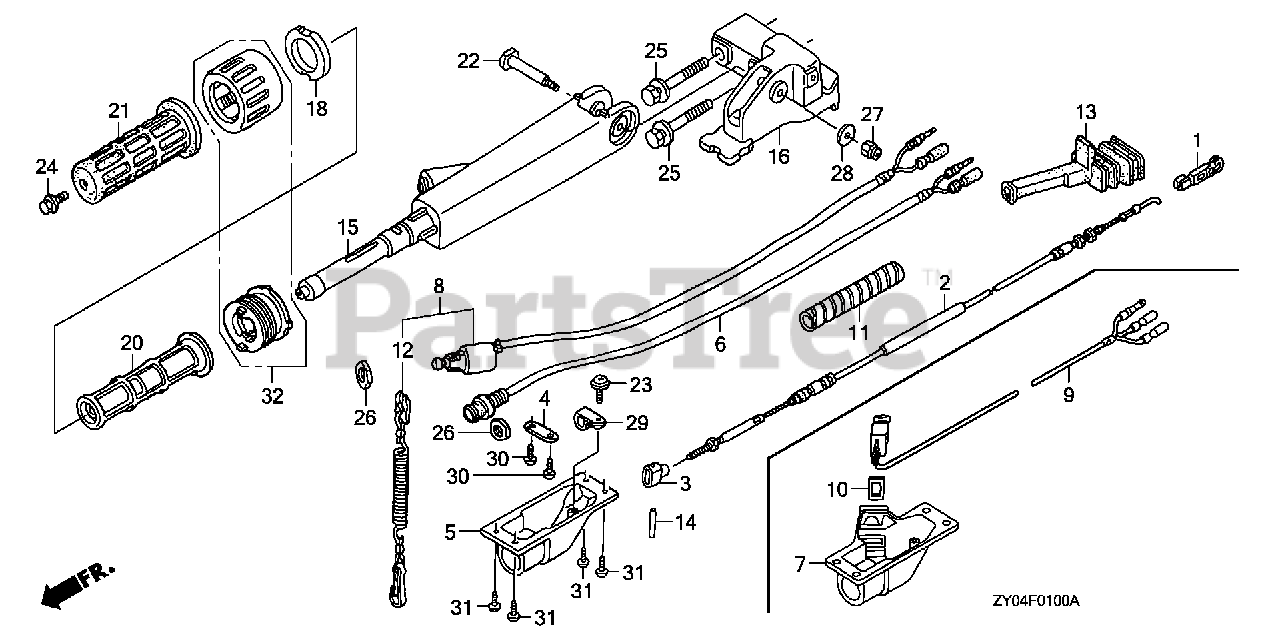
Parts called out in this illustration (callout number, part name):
1	LINKAGE, PIVOT
2	CABLE, THROTTLE
3	PIVOT, THROTTLE CABLE
4	PLATE, SHIFT
5	COVER, STATOR
6	SWITCH ASSY., STARTER
8	SWITCH ASSY., EMERGENCY STOP
11	TUBE, SPIRAL B
12	WIRE, EMERGENCY
13	GROMMET, OIL CASE (A)
14	PIN, THROTTLE CABLE
15	HANDLEBAR *NH246* (LOOSY GRAY)
16	BRACKET, HANDLEBAR *NH246* (LOOSY GRAY)
17	GRIP ASSY., THROTTLE FRICTION
18	PAD, THROTTLE FRICTION
19	BLOCK, THROTTLE FRICTION
20	PIPE, GRIP
21	RUBBER, GRIP
22	SCREW, HANDLE PIVOT
23	SCREW, TAPPING (4X10)
24	BOLT, FLANGE (6X12)
25	BOLT-WASHER (10X55)
26	NUT, HEX. (16MM)
27	NUT, SELF-LOCK (8MM)
28	WASHER (8MM)
29	CLIP, WIRE HARNESS (6.3MM)
30	SCREW, TAPPING (4X12)
31	SCREW, TAPPING (4X12)
32	GRIP ASSY., THROTTLE FRICTION
